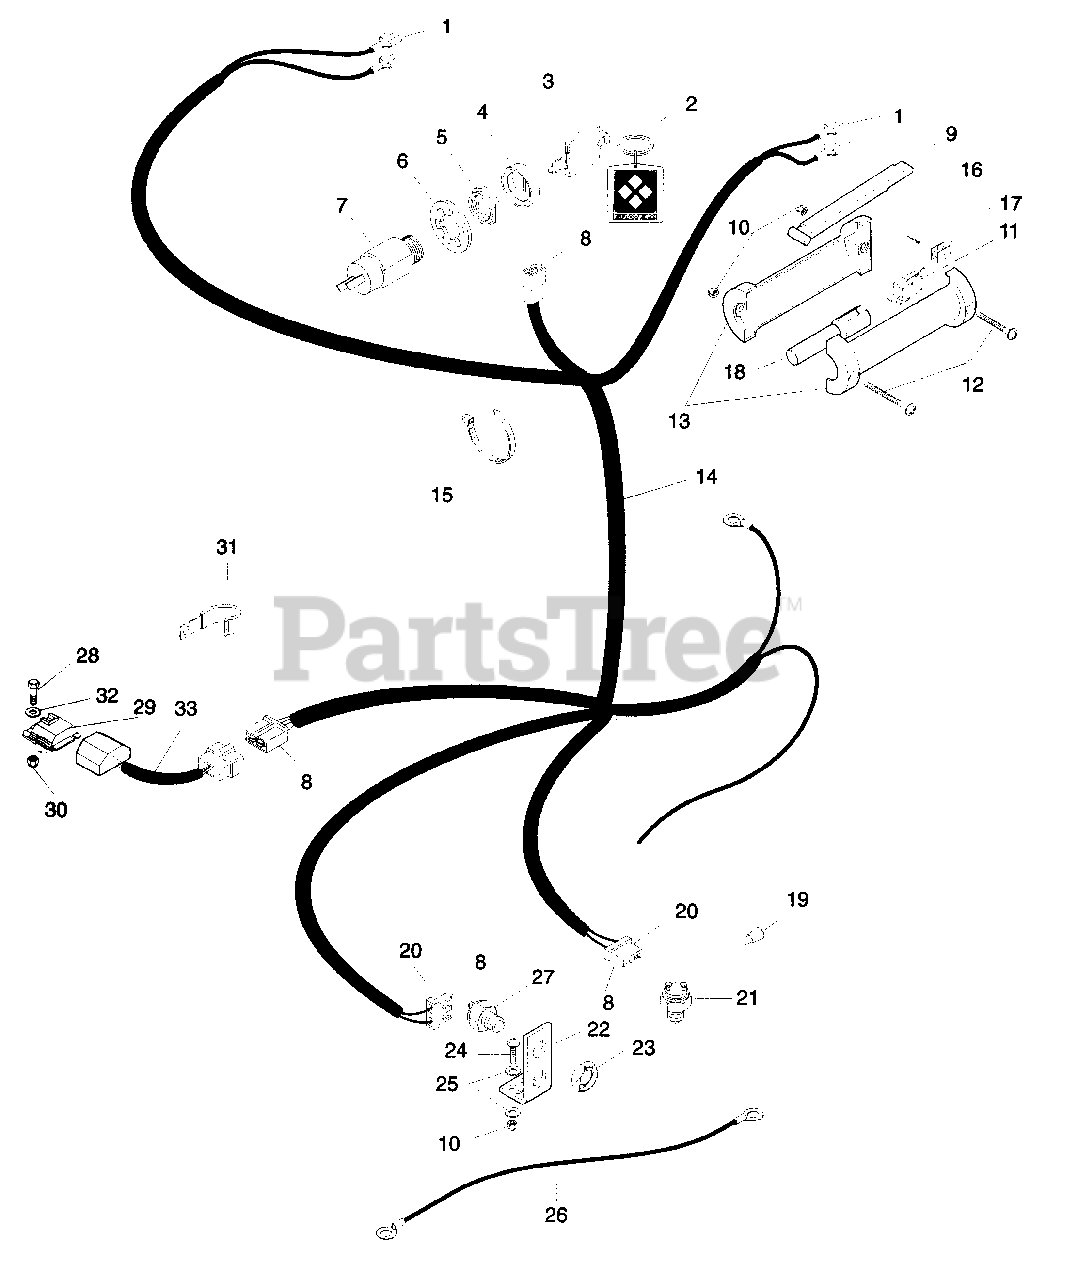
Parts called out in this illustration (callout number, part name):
1	Terminal, Female
2	Key Chain
3	Ignition Switch Key
4	Cap-Ignition Switch
5	Nut-Panel .625-32
6	Washer-Lock .625
7	Key Switch Assembly
8	Terminal
9	Lever
10	Nut-Locking-Nylon w/Insert 10-24
12	Screw-Machine, Pan Head 10-24 x 1.50
13	Handle, Left Hand & Right Hand
14	Harness, Wiring Pro Recoil
15	Tie Wrap, Black
16	Pin-Roll .094 x .750
17	Holder, Switch
18	Insert, Handlebar
19	Nut-Connector
20	Connector, 2-Wire Switch
21	Switch-Neutral Start (N.C.)
22	Bracket, Interlock Switch
23	Nut-Stamped .56-18
24	Bolt-Hex 10-24 x .75
25	Washer-Flat-Steel .219 x .50 x .049
26	Wire, Ground
27	Switch-Neutral Start
28	Bolt-Hex .25-20 x .75 Grade 5
29	Module
30	Nut-Locking-Center .250-20
31	J-Clamp
32	Washer-Flat-Steel .344 x .688 x .065
33	Adapter Harness
33	Adapter Harness, Interlock
34	Kit, Interlock Module
34	Kit, Interlock Module Coil
